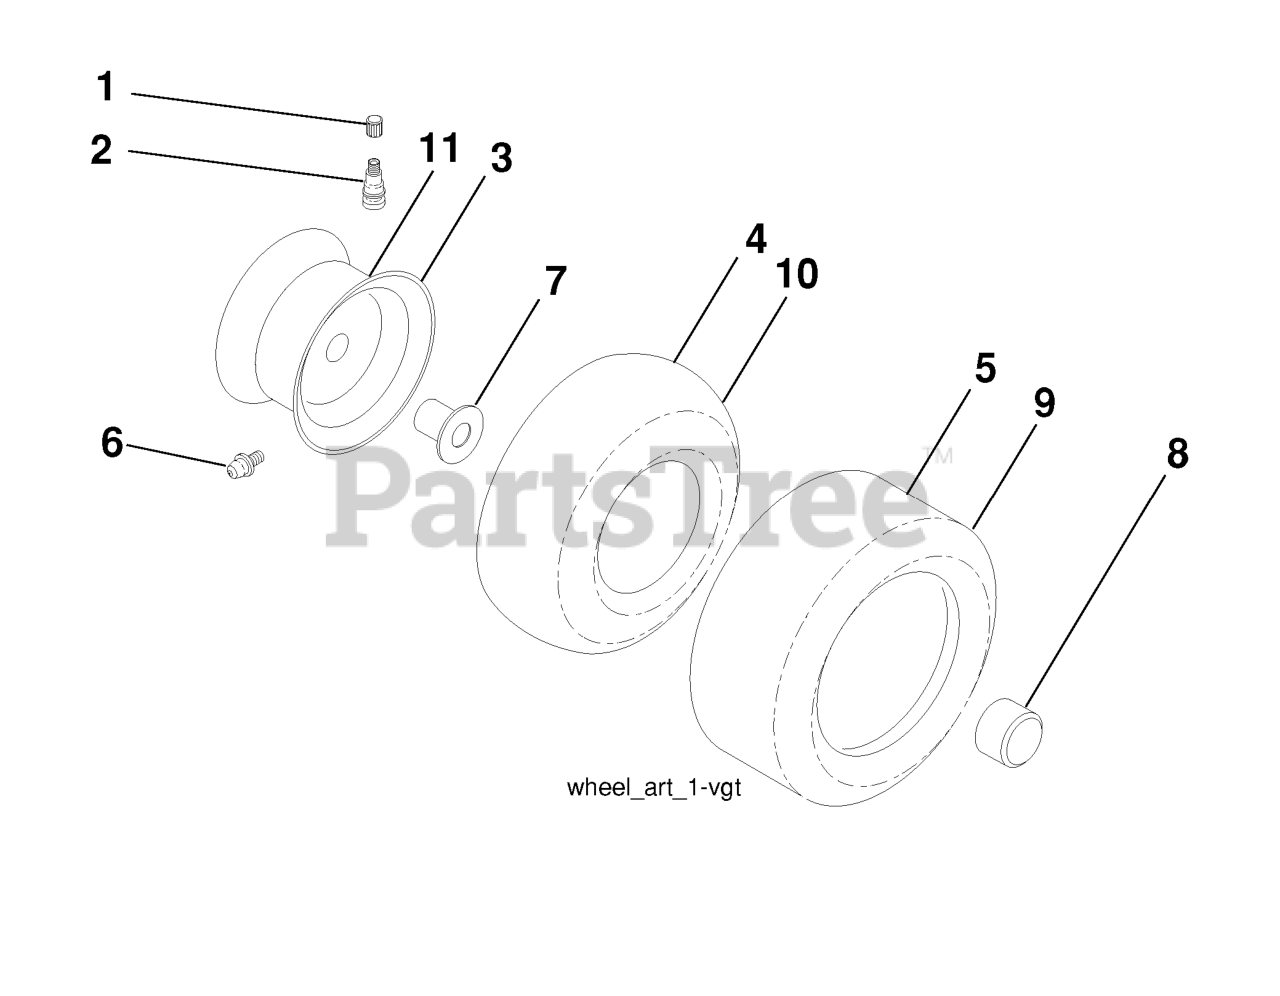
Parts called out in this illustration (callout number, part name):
2	VALVE STEM LT
3	RIM ASM 6" FRONT SILVER
4	TUBE.5.3/4.5/6
5	TIRE HEAVY DUTY
6	FITTING LT
7	BEARING T
8	CAP, AXLE BLK
9	TIRE.18X9.5-8 TURF SAVER
10	TUBE
11	RIM ASM 8" REAR SILVER
